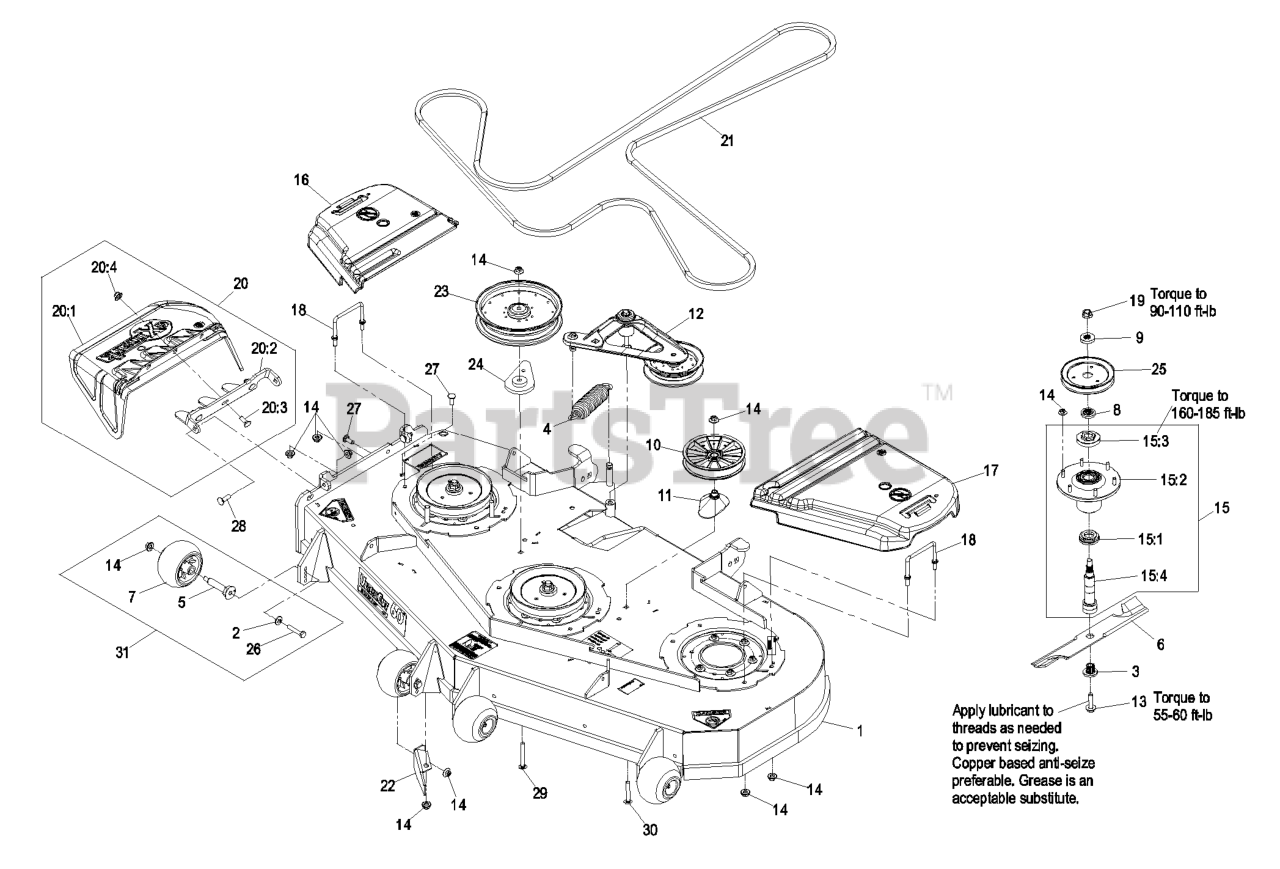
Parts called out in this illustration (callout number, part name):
2	WASHER-BELLEVILLE
3	BUSHING,SPLINED
7	ROLLER-SCALP, ANTI
8	SPACER,SPLINED STEPPED
9	SPACER,SPLINED
10	PULLEY,IDLER 6"
11	SPACER-PULLEY
13	SCREW,SEMS 1/2-20 X 2.19
14	Nut-Nyloc 3/8-16 Flg
15	ASM,SPINDLE HOUSING
15:1	GUARD,BOTTOM
15:2	ASM,CUTTER HOUSING
15:3	NUT, SPINDLE 7/8-14
15:4	SPINDLE,DOUBLE SPLINE
16	COVER-BELT, RH
17	COVER-BELT, LH
18	WIREFORM-COVER
19	NUT-FLANGE, CENTERLOCK
20	ASM,DISCHARGE CHUTE
20:1	CHUTE,DISCHARGE
20:2	BRACKET,DISCHARGE CHUTE
20:3	SCREW-CARR
20:4	Nut-Nyloc 3/8-16 Flg
21	BELT,V-5V-198.75
22	BAFFLE,DISCHARGE 52/60
23	PULLEY-IDLER
24	SPACER-IDLER
25	SHEAVE,BLADE DRIVE 7.25
26	SCREW-HH
27	SCREW-CARR
28	Bolt-Carriage 3/8-16 X 1 1/4
29	SCREW-CARR
30	SCREW-CARR
32	Asm, Deck Complete 606
